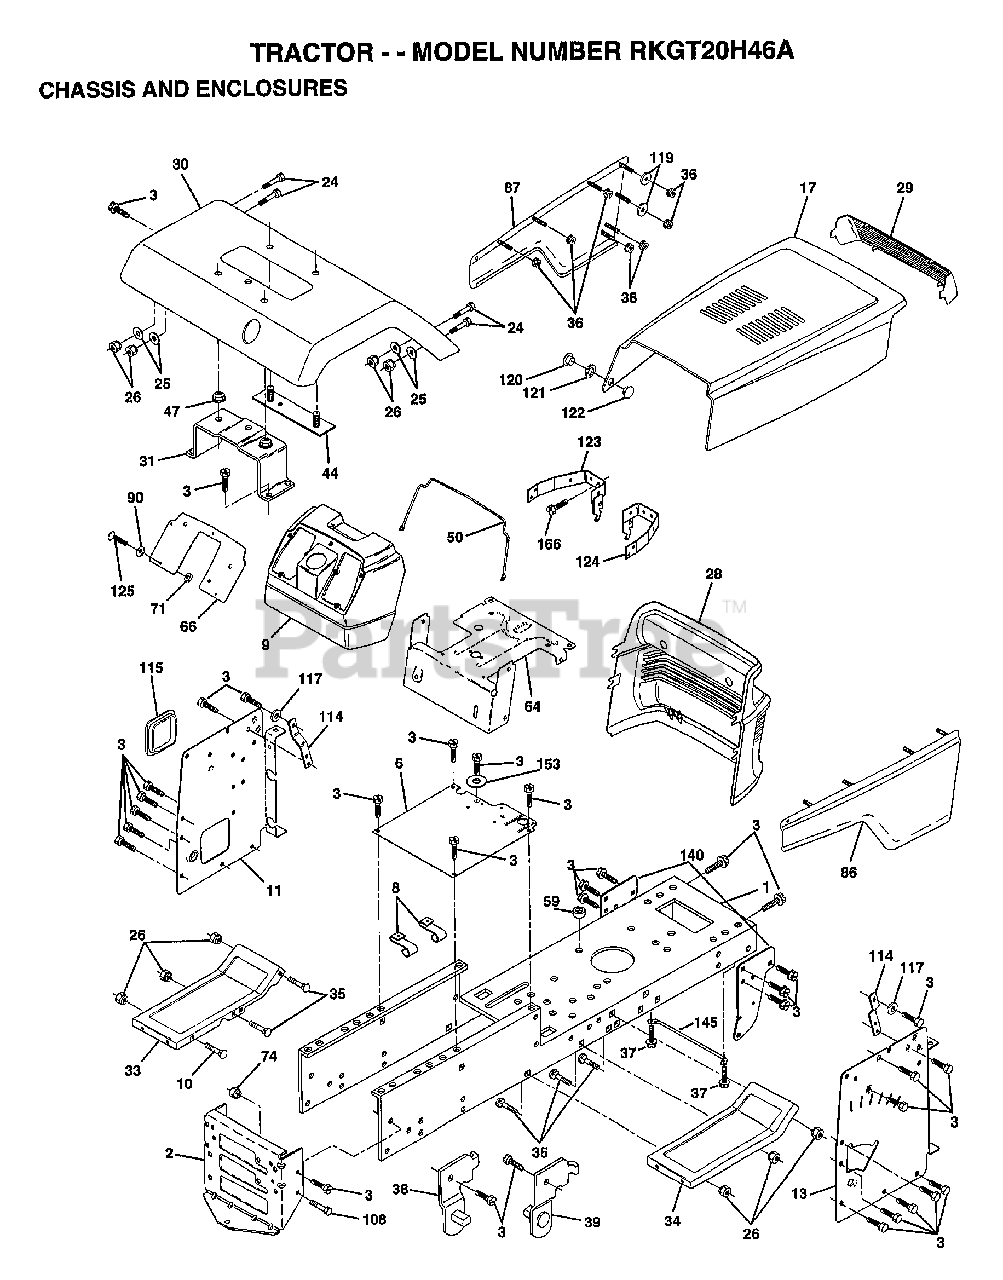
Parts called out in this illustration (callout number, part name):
1	CHASSIS.STAMPING
3	SCREW
6	SADDLE
8	"CLIP,INSULATOR"
9	DASH.PLASTIC.BLK
11	DASHBRD.PANEL.LH
13	DASHBRD.PANEL.RH
17	HOOD.GRILLE.ASM.PNT
24	BOLT
25	WASHER
26	NUT
29	LENS.YT.GT.SEARS
31	BRKT.ASM.FENDER
34	FOOTREST.RH.PNT
35	BOLT
36	PAL NUT LT
37	SCREW LT
38	BRACKET ASM LH
39	BRACKET ASM RH
43	WASHER T
44	STRAP ASM FENDER
47	NUT-PUSH YT
50	ROD.SUPT.HOOD 1PC
64	DASH.LOWER.LT
66	PLATE.SIKLSCREEN.DASH
71	NUT HXKEP 1/4X20
86	ASSY.PANEL.SIDE.RH
90	WASHER PM
114	BRACKET.SUPT.DASH
115	COVER ACCESS
117	WASHER.SERRATED.
119	WASHER
120	RIVET.RATCH.FEMAL
121	WASHER.NYLON
122	RIVET.RATCHET.MAL
123	BRKT ASM PIVOT LH
124	BRKT ASM PIVOT RH
125	SCREW
140	BRKT SUSPENSION
145	"ROD POVOT,CHASSIS"
153	WASHER GT
166	"SCREW,HWHD.HI-LO#13-16X3/4"
